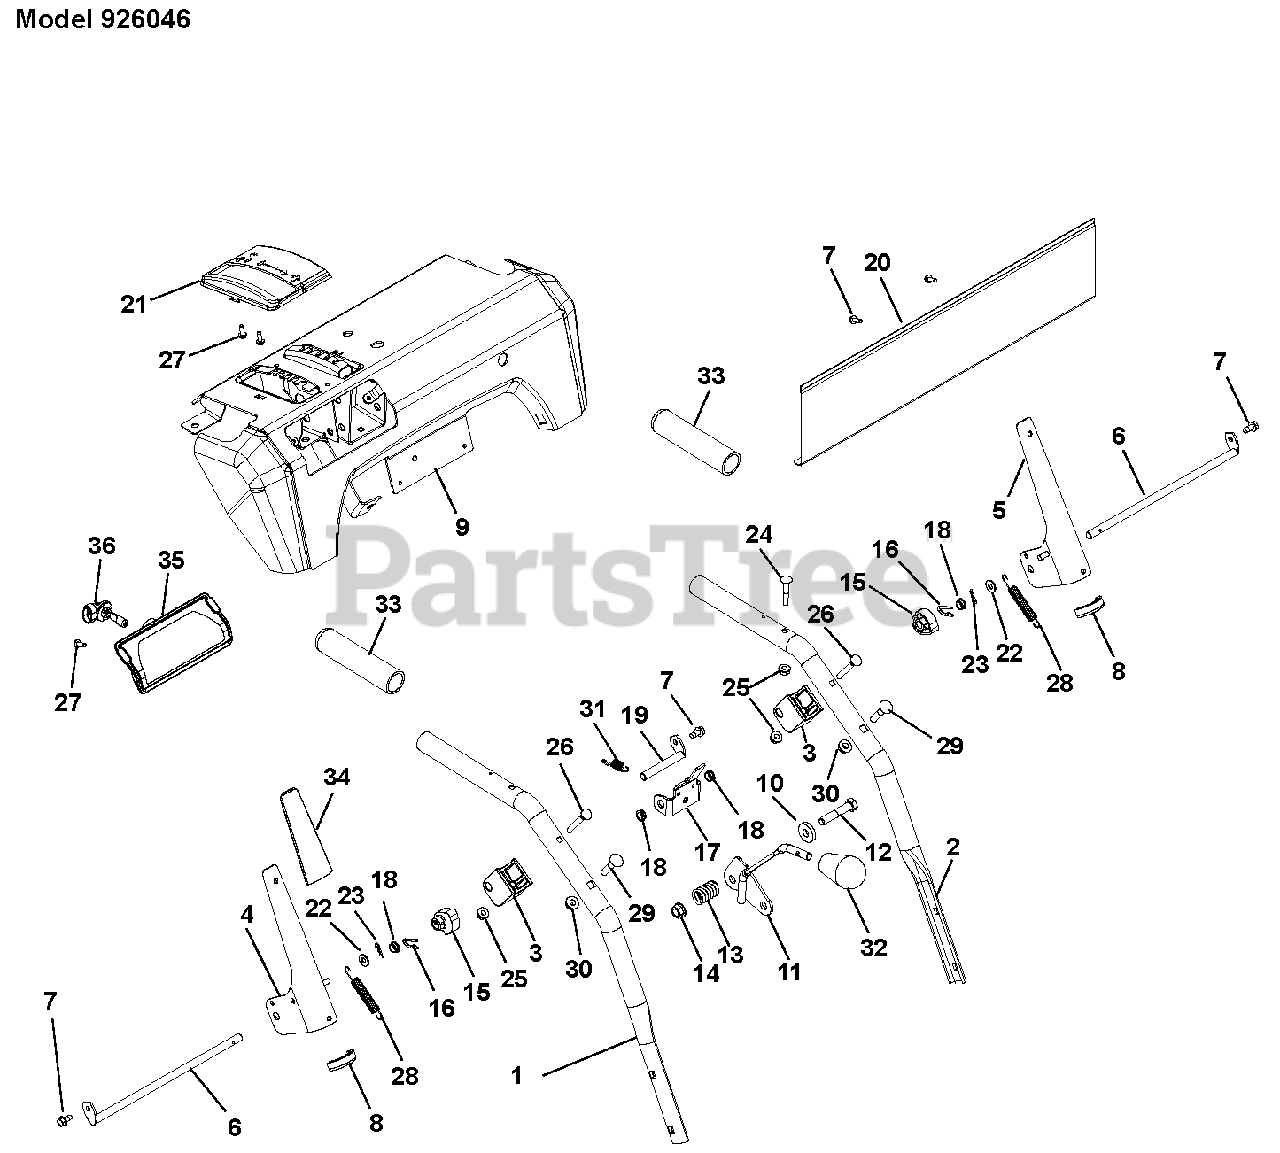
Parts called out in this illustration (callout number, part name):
1	Handlebar, Upper, Right Hand
2	Handlebar, Upper, Left Hand
3	Clutch Paddle Block
4	Clutch Handle, Right Hand
5	Clutch Handle, Left Hand
6	Rod, Paddle Mount
7	Screw, Tapping Hex Washer Head Thread Rolling .25-20 x .50
8	Edging, Clutch Handle
9	Control Panel with Decal
10	Washer, Flat Steel .406 x 1.00 x .188
11	Lever, Shift
12	Bolt, Hex .38-16 x 2.00
14	Nut, Locking Top Flange .38-16
15	Cam, Interlock
16	Pin, Spring Clip
17	Interlock Arm
18	Bushing, Polyliner
19	Rod, Pivot
20	Brand Plate
21	Shift Bezel
22	Washer, Flat Steel .281 x .62 x .065
23	Pin, Hair, Internal .06 x .18 x .77
24	Bolt, Round Head Extra Long Square Neck .25-20 x 1.25
25	Nut, Locking Top Flange .25-20
26	Bolt, Round Head Extra Long Square Neck .25-20 x 2.00
27	Screw, Tapping Hex Head Boss #10 x .50
29	Bolt, Round Head Square Neck .31-18 x 1.50
30	Nut, Locking Top Flange .31-18
33	Handle Grip
34	Sleeve, Clutch Handle
35	Headlight Assembly (Includes Item 36)
36	Bulb, Light (Included in Item 35)
